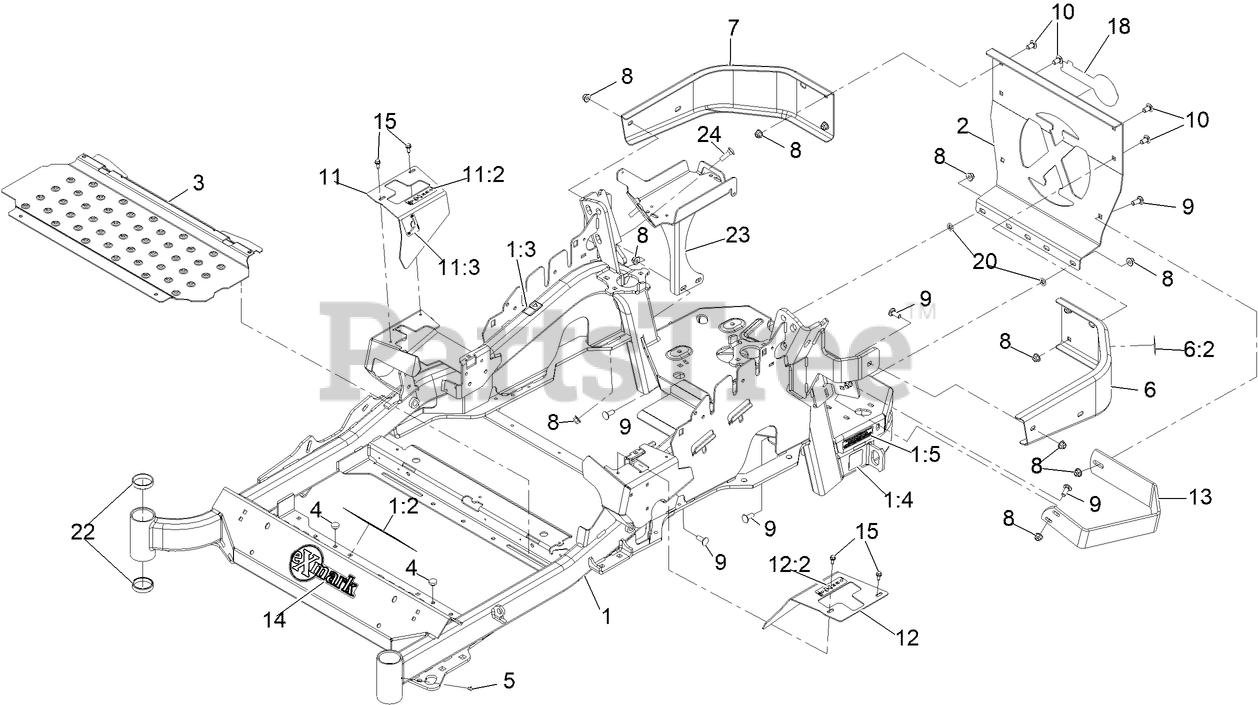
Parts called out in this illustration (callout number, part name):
1	Mainframe Service ASM - 48/52
1:2	DECAL-DANGER
1:3	DECAL-WARNING
1:4	DECAL-HAZARD, PINCHED FINGER
1:5	DECAL-ARRESTOR, SPARK
2	PLATE,REAR GUARD
6	LH BUMPER ASM
6:2	DECAL-WARNING
7	BUMPER-RH
8	NUT-HF, NI
9	SCREW-CARR
10	SCREW-CARR
11	RH MOTION CONTROL COVER ASM
11:2	DECAL-CONTROL, MOTION
11:3	DECAL-PARK BRAKE, CE
12	LH MOTION CONTROL COVER ASM
12:2	DECAL-CONTROL, MOTION
13	GUARD-MUFFLER
14	DECAL-EXMARK
15	SCREW-HWH
18	DECAL, EXMARK LOGO
20	NUT-PUSH
22	CUP-BEARING
23	BATTERY MOUNT ASM
24	BOLT-CARR
